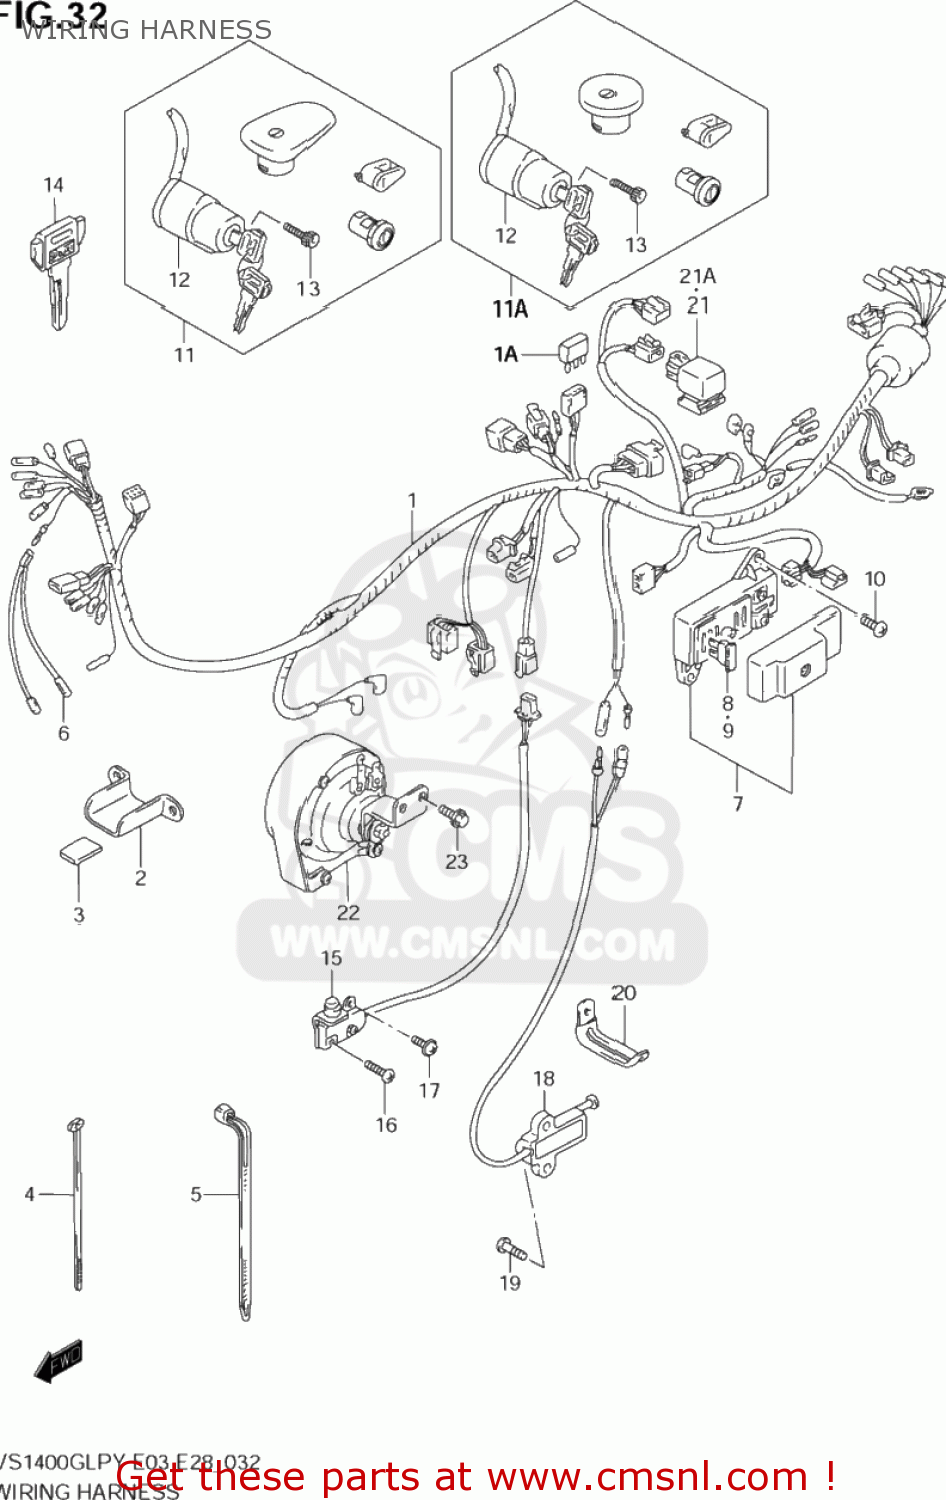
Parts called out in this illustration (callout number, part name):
1	HARNESS,WIRING
1A	DIODE(STANLEY DE8804)
2	GUIDE,WIRING HARNESS
3	CUSHION
4	CLAMP
5	CLAMP(L:125)
6	WIRE,CLUTCH SW CONNECTOR
7	BOX ASSY,FUSE
8	FUSE (25A)
9	FUSE(10A)
10	SCREW
11	LOCK SET
11A	LOCK SET
12	SWITCH ASSY,IGNITION
13	BOLT
14	KEY,BLANK(TYPE:C)
15	SWITCH ASSY,STOP LAMP
16	SCREW 4X16
17	SCREW
18	SWITCH ASSY,SIDE STAND
19	SCREW
20	CLAMP(L:45)
21	RELAY ASSY
21A	RELAY ASSY
22	HORN ASSY
23	BOLT
